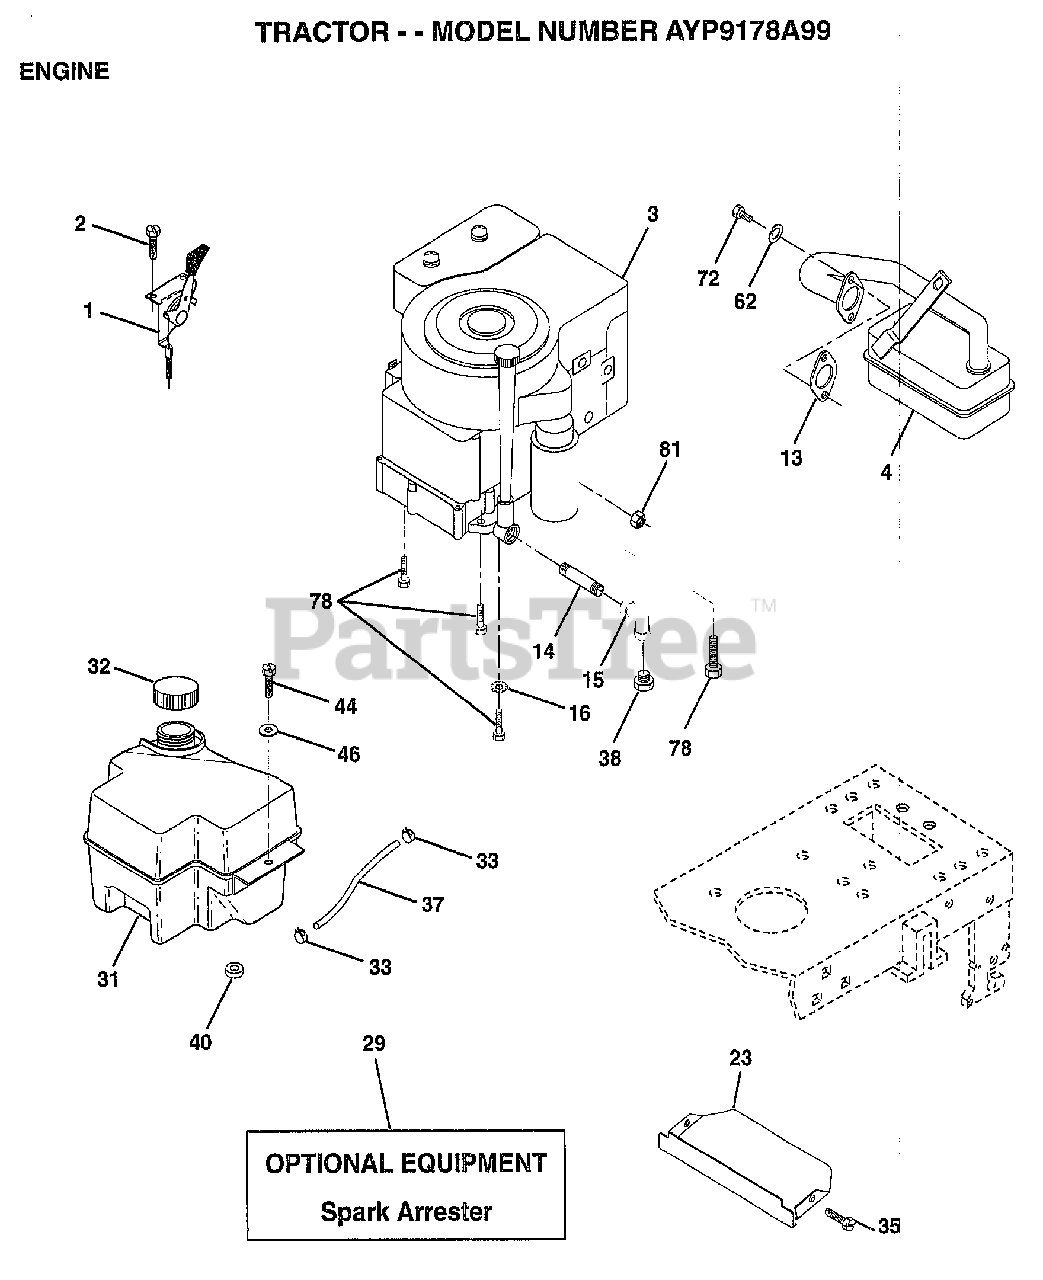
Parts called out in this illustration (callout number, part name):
1	CONTROL THROTTLE
2	SCREW LT
4	MUFFLER
13	GASKET ENG 1 313 LD TIN PLATED
14	PIPE NIPPLE
15	ELBOW
16	LOCKWASHER
23	SHIELD.BRN/DBR.GD
31	TANK.FUEL.FRONT.
32	CAP ASM FUEL
33	HOSE CLAMP
35	SCREW
37	LINE FUEL
44	SCREW HEX CRT
46	WASHER
62	LOCKWASHER
72	SCREW
78	SCREW
81	NUT
